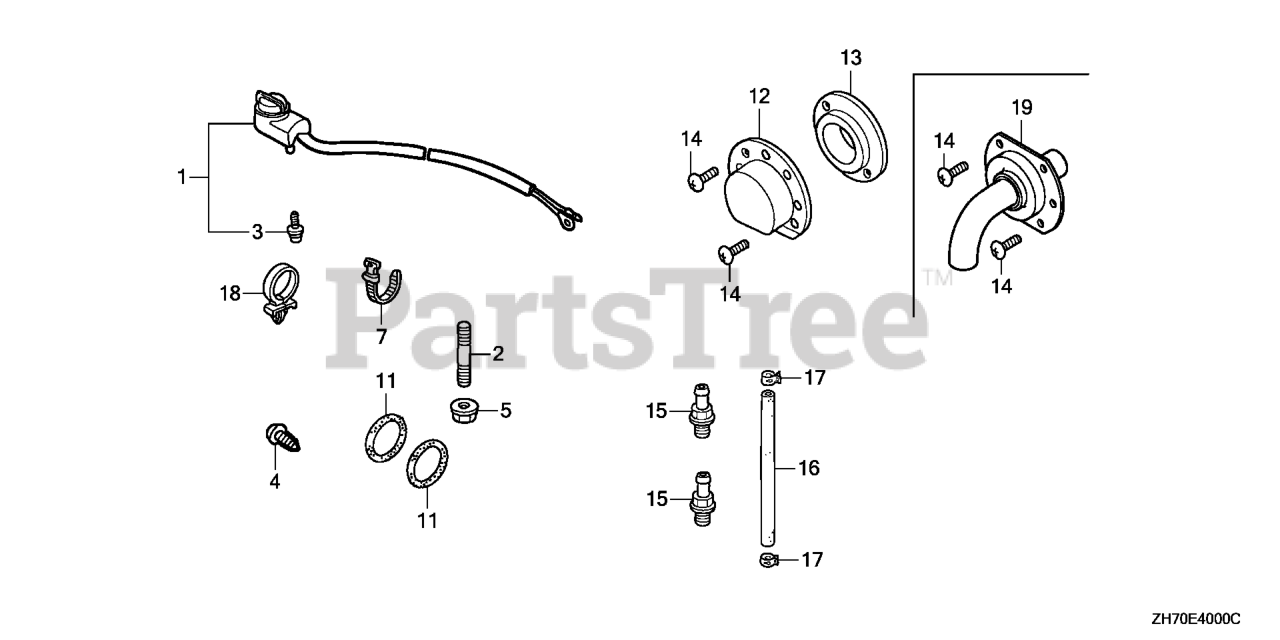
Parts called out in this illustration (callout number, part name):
12	DEFLECTOR
13	GUIDE, MUFFLER
14	SCREW, TAPPING (4X8)
